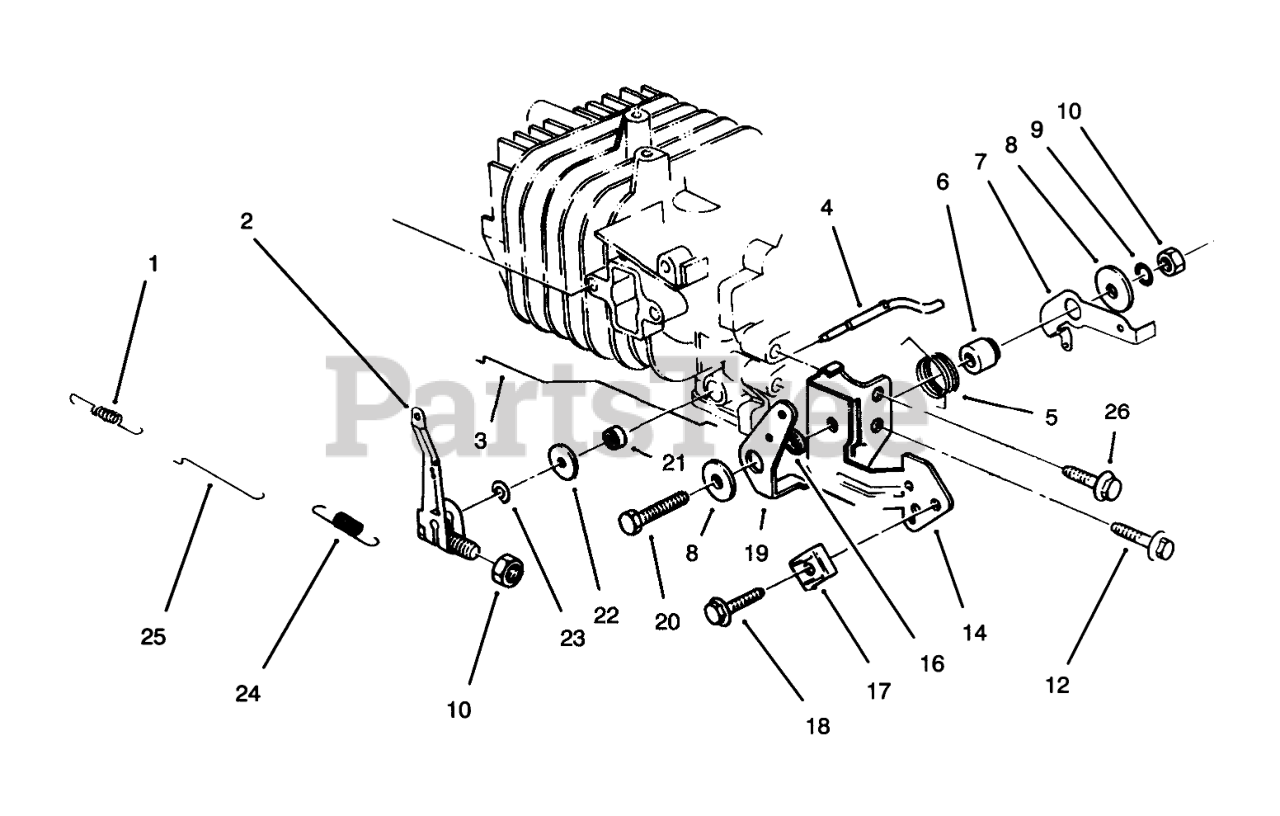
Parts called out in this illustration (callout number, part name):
1	SPRING
2	ARM-GOVERNOR
3	ROD-CHOKE
4	Shaft-Govemor
5	SPRING-CHOKE LEVER
6	Gov Lever Spacer
7	LEVER-SPRING, GOVERNOR
8	WASHER
9	LOCKWASHER
14	BRACKET-THROTTLE, CONTROL
16	SPACER-CHOKE LEVER
17	CLAMP
19	LEVER-CONTROL, CHOKE
21	SEAL-OIL
22	WASHER
23	E-RING
24	SPRING-GOVERNOR
25	ROD-CARBURETOR
